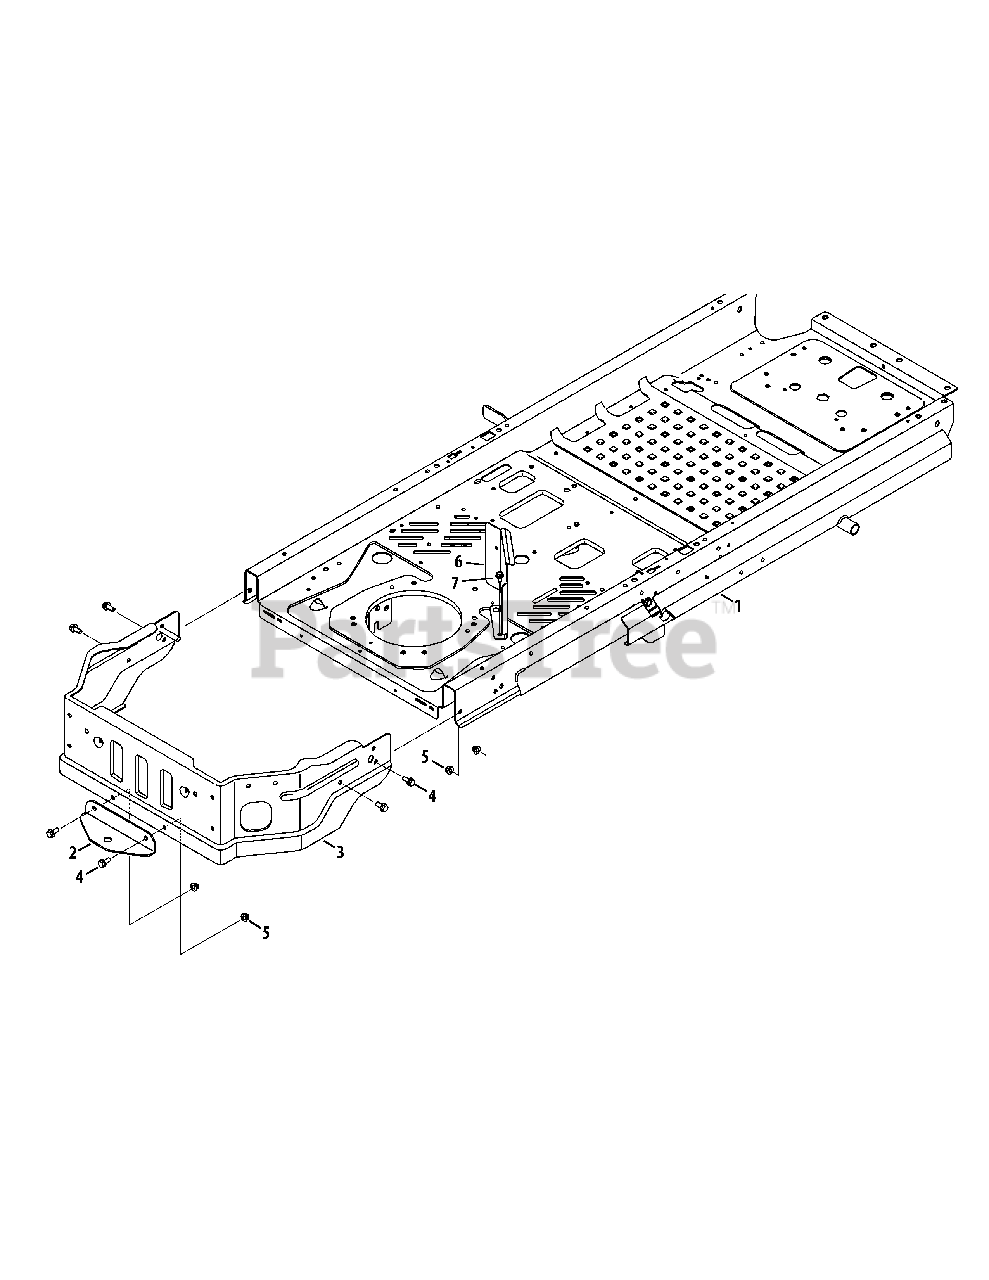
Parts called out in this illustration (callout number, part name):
1	Frame Assembly
4	Screw, 5/16-18, Hexflange
5	Flange Lock Nut, 5/16-18
6	Engine Heat Shield
7	Hex Washer Screw, 1/4-20 x .625
